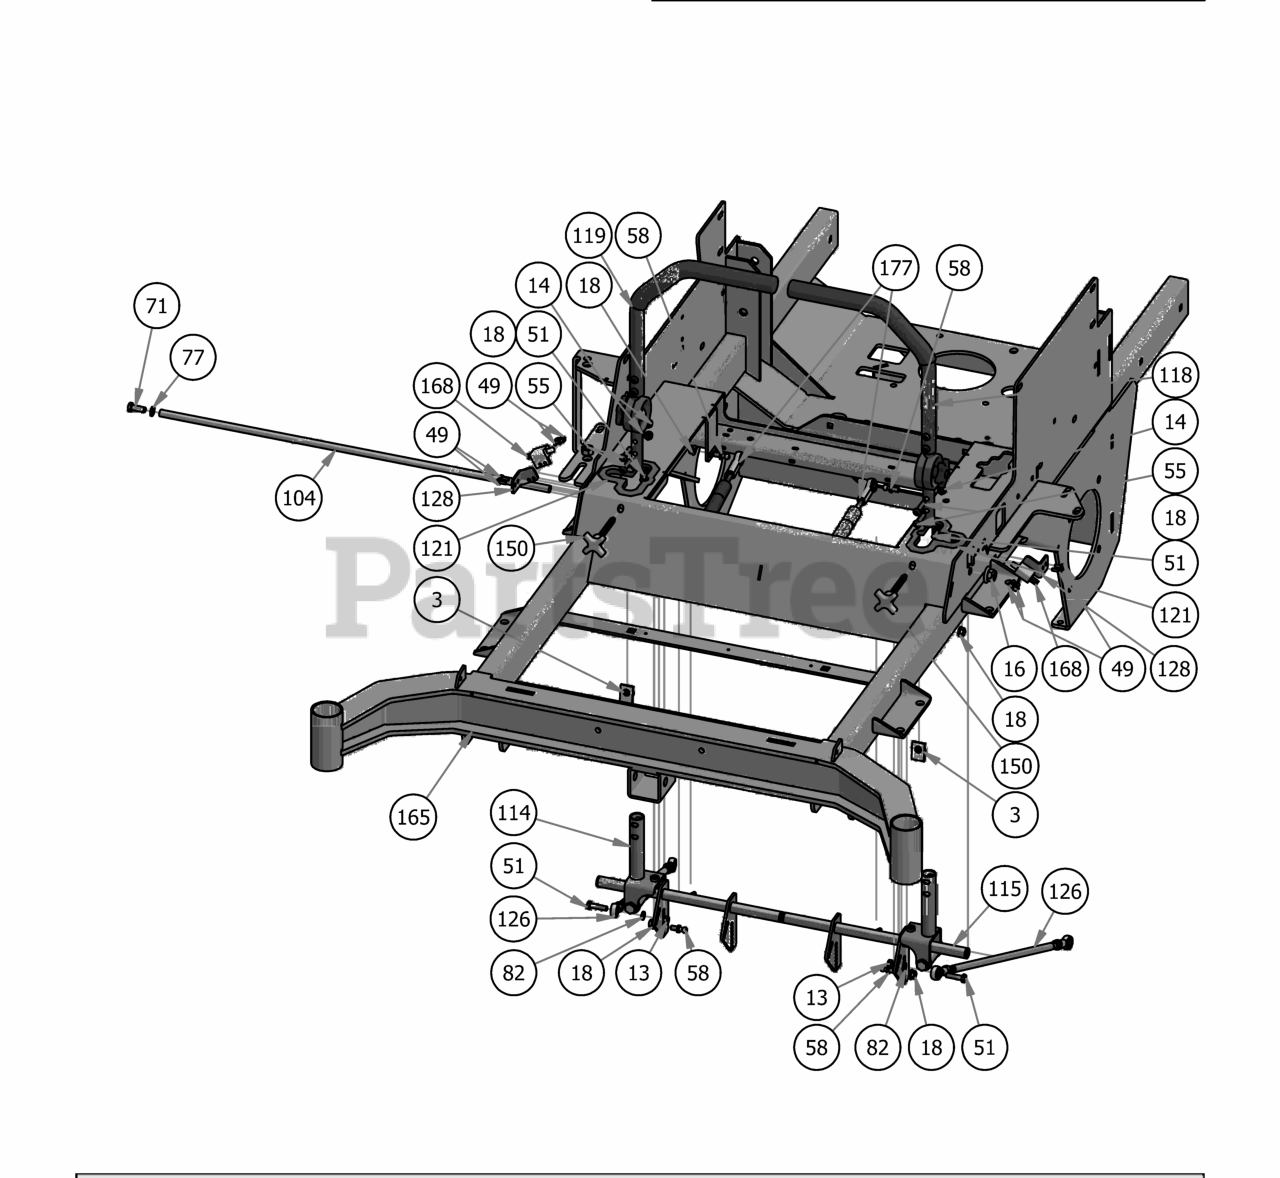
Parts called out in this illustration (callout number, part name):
3	Extruded Nut 3/8"-16 3/4" Hole Center With Patch
14	5/16-18 Nylock Insert Locknut
16	1/2-13 Nylon Flange Nut
18	5/16" Flange Nut
49	12-24x 1/2 HWH Bolt
51	5/16 x 1 1/4 Hex Bolt
55	5/16-18 BHCS, TORX DRIVE
58	10mm Damper Ball Stud-Steering
71	3/8" x 1" Hex Bolt
77	3/8" Lock Washer
82	5/16" Lock Washer
104	2019 Steering Actuator Rod
114	2019 R Series RH Arm Rod Assembly
115	2019 R Series LH Arm Rod Assembly
118	2019 Left Hand ADJ. Steering Arm Kit
119	2019 Right Hand ADJ. Steering Arm Kit
121	Snap-In Bushing-2019
126	2019 Outlaw Rigid Push Rod Assembly
128	2019 Arm Switch Bracket
150	Speed Limiting Knob 3/8-16X 3"
165	2019 Rigid Frame
168	Safety Switch
177	Steering Damper
